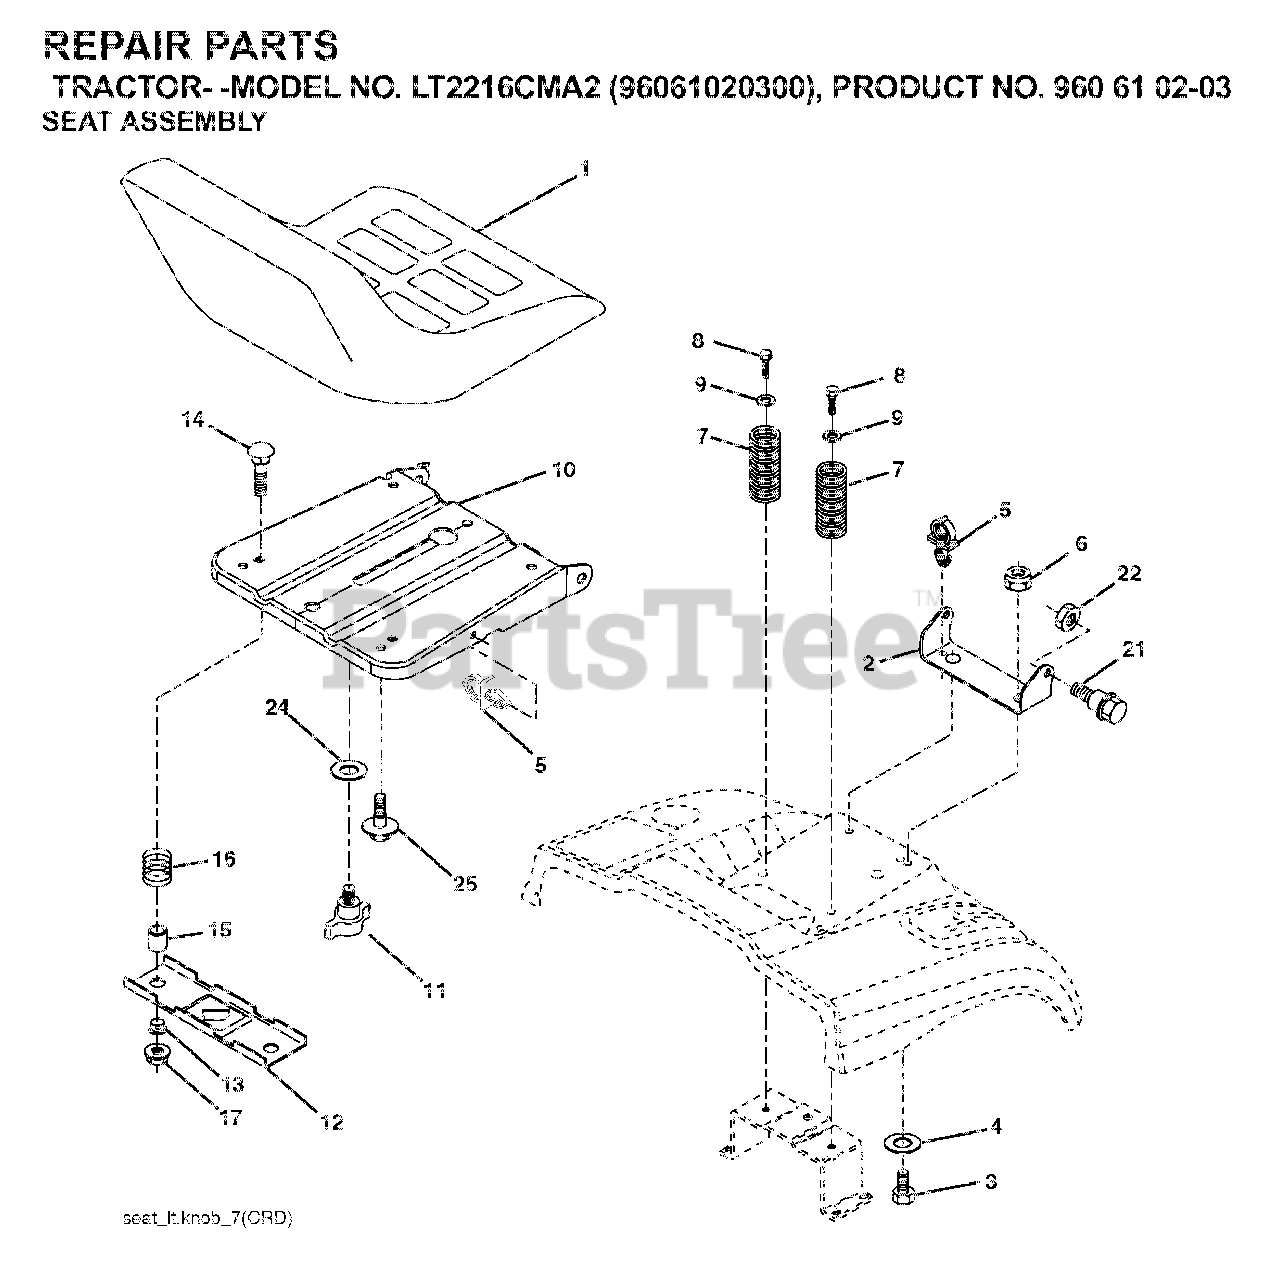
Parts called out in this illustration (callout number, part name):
1	SEAT.XG150.BLK.KB/SLD.NO-LOGO
2	SEAT PIVOT BRKT
4	WASHER PM
5	PUSH CLIP
6	NUT
7	SPRING COMPRESSION
8	SCREW 3/8-16X1
9	WASHER
10	PAN.ASM.SEAT.1SLOT
11	KNOB.SEAT.ADJ.WINGNUT
12	BRKT.MNTNG.SWITCH.SEAT
14	BOLT.ROUND.HEAD.SQUARE.NECK
15	SPACER SPLIT
16	SPRING COMPRESSED
17	NUT T
21	BOLT.SHOULDER.5/16-18
22	NUT.71038.31-18.HEX.NYLOCK
25	BOLT,SHOULD
